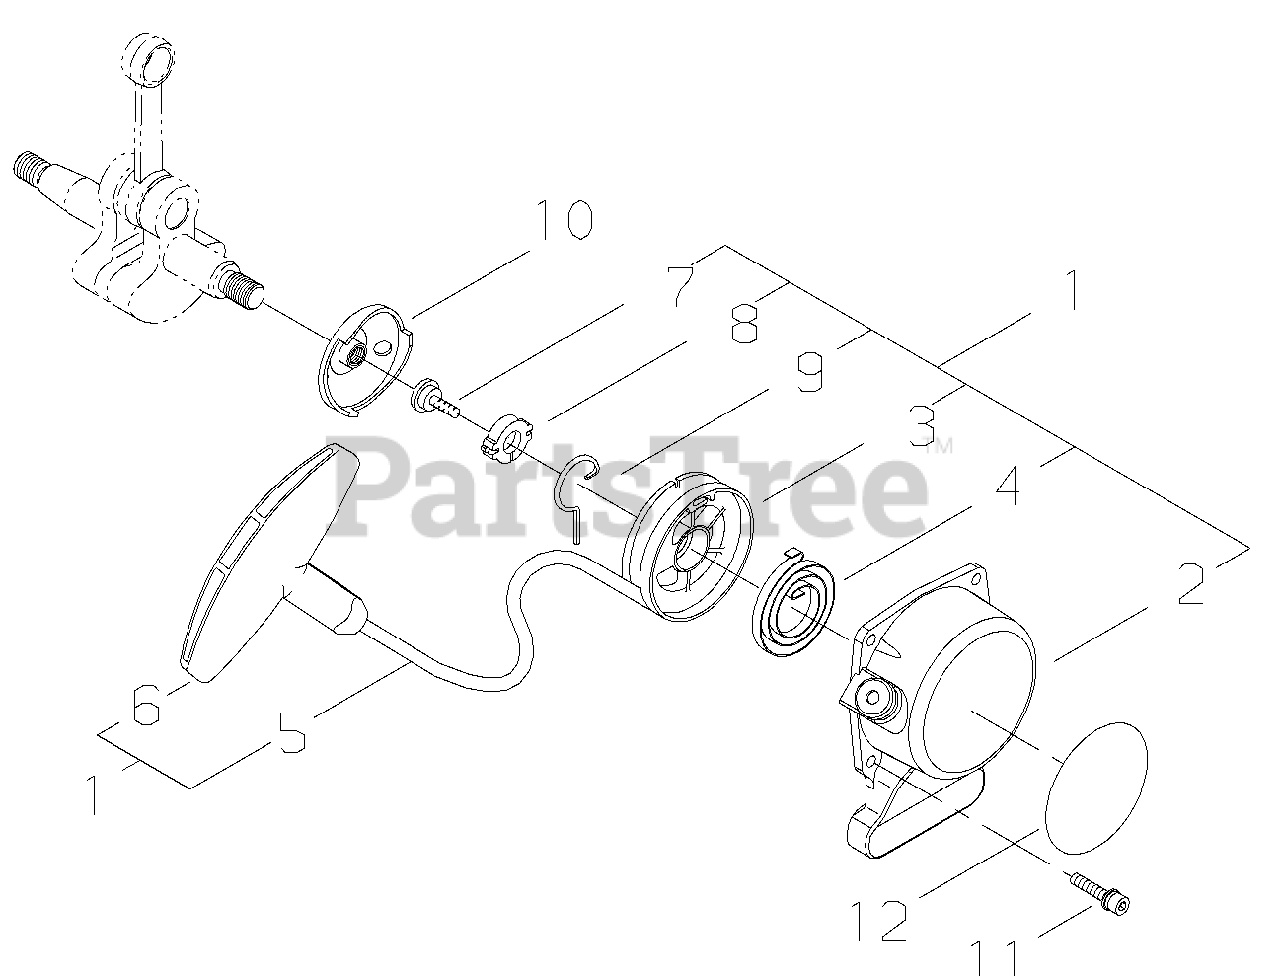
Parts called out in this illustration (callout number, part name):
2	CASE, RECOIL STARTER
3	REEL, ROPE
4	SPRING, RECOIL
5	ROPE, STARTER
6	GRIP, STARTER
7	SCREW 5
8	WASHER 5
9	ARM, SWING
10	PULLEY, STARTER
11	BOLT M4×14
12	LABEL, RECOIL C4
